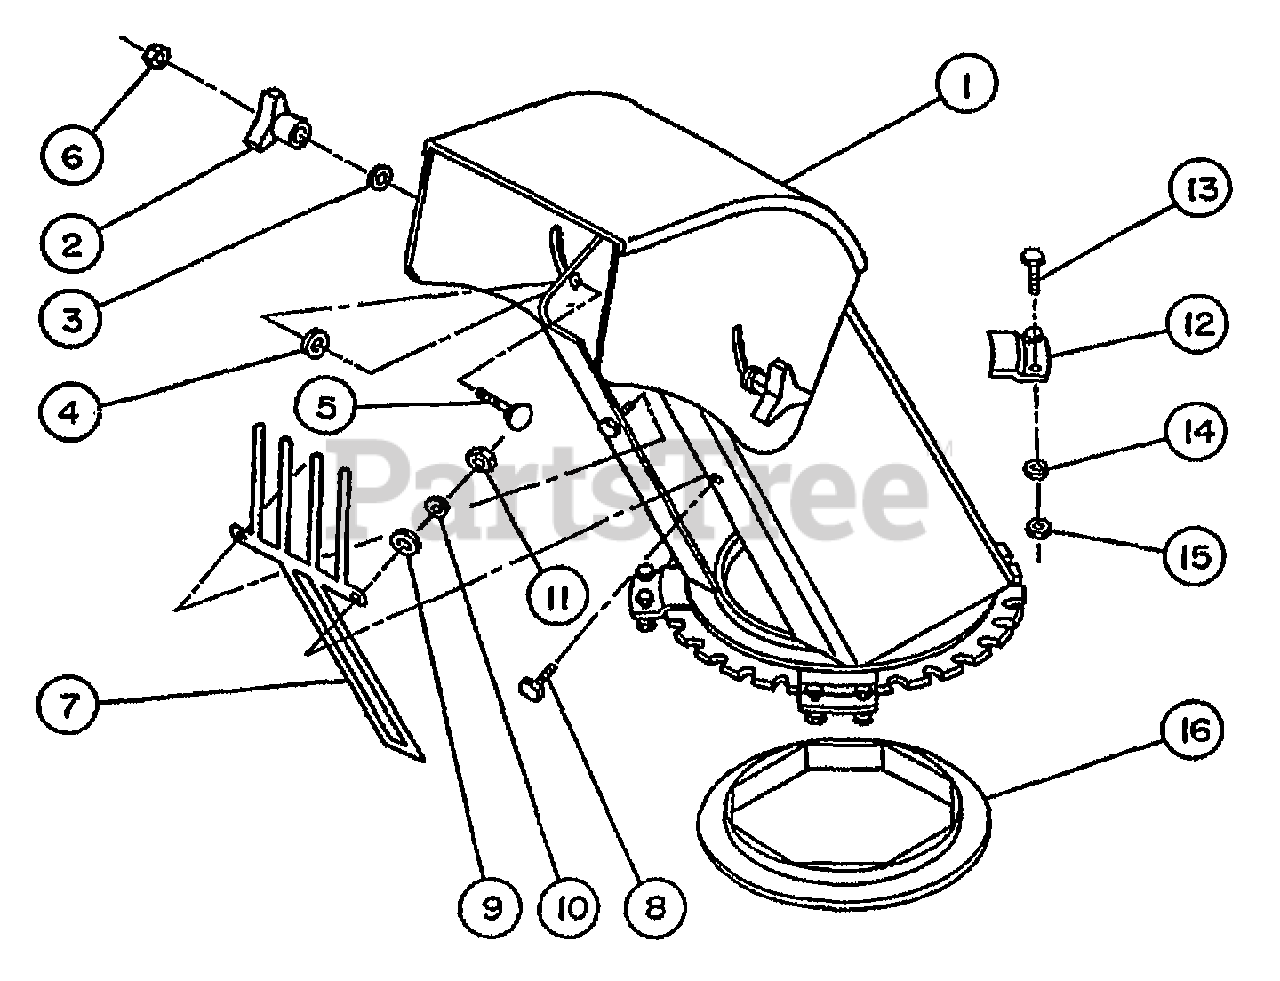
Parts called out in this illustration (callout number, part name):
1	CHUTE-BASE & KNOBS
3	BUSHING-NYLON
4	WASHER-.87X.34X.06 NYLON
5	BOLT-CARR .312
6	NUT-H/LK 5/16-18 NYLOCK
7	GUARD-HAND
8	SCR-HH 1/4-20X.75 G5 ZP
9	WASHER-FLAT 5/16 SAE
10	WASHER-LK .25 ZP
11	NUT-HEX 1/4-20 ZP
12	PLATE-RETAINING
13	SCR-HH 1/4-20X.5 GR5 YEL
13	SCR-HH 1/4-20X.75 G5 ZP
14	WASHER-LK .25 ZP
15	NUT-HEX 1/4-20 ZP
16	RING-NYLON
